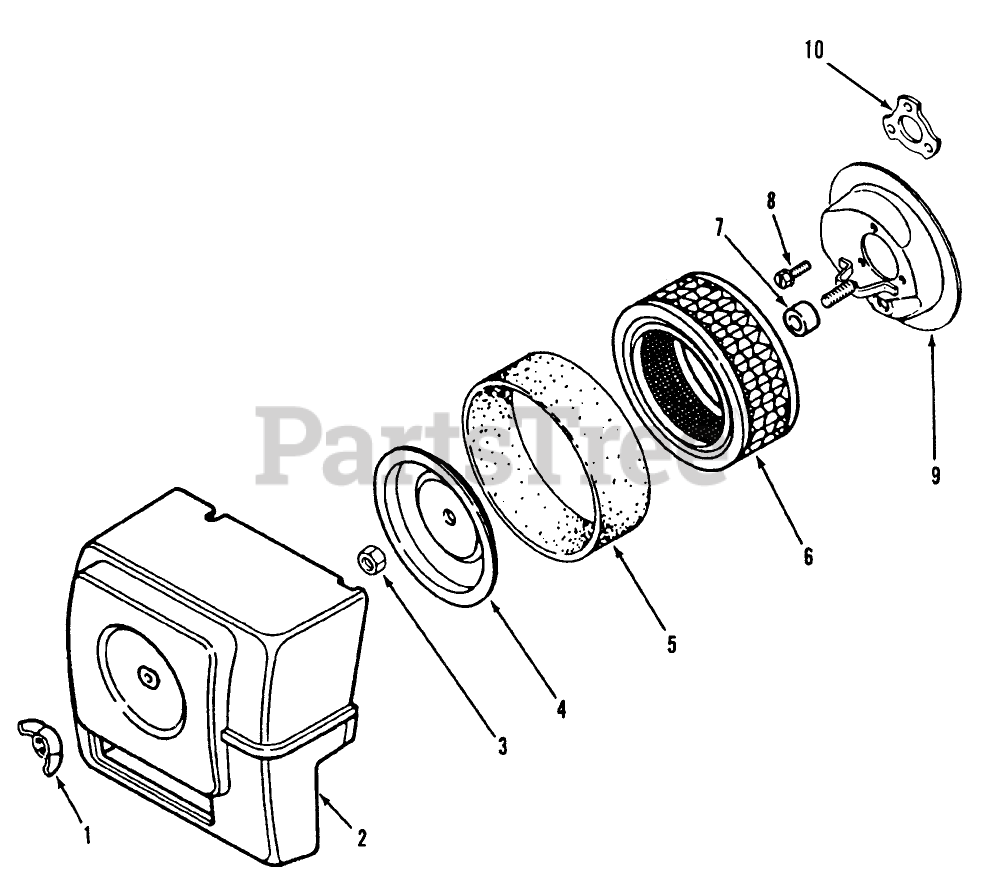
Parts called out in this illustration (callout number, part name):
1	Wing Nut 1/4-20
2	Air Cleaner Cover
3	Jam Nut
4	Cover-Element
5	Element
6	Element
8	Screw
9	Base-Air Cleaner
10	Air Horn Gasket
